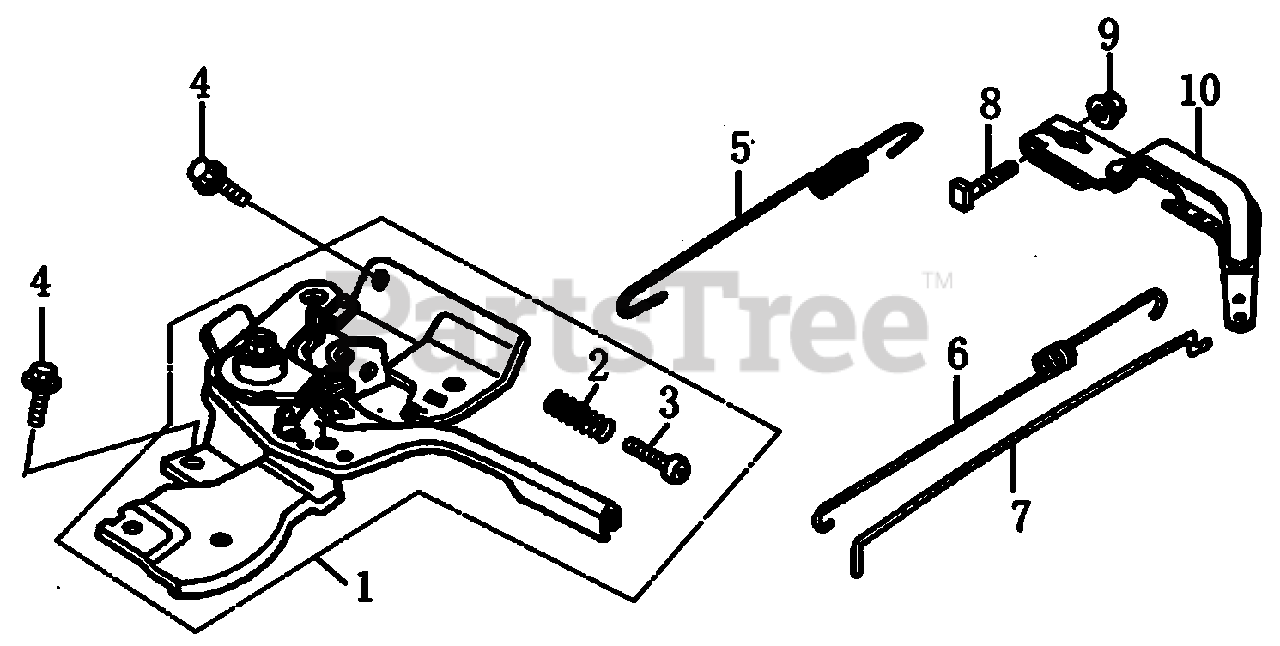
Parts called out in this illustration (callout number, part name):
1	CONTROL ASSY.
3	SCREW , 5X35
4	BOLT, FLANGE
5	SPRING, GOVERNOR
6	SPRING, THROTTLE RETURN
7	ROD, GOVERNOR
8	BOLT, QUADRATE HEAD
9	NUT, FLANGE
10	ARM, GOVERNOR
